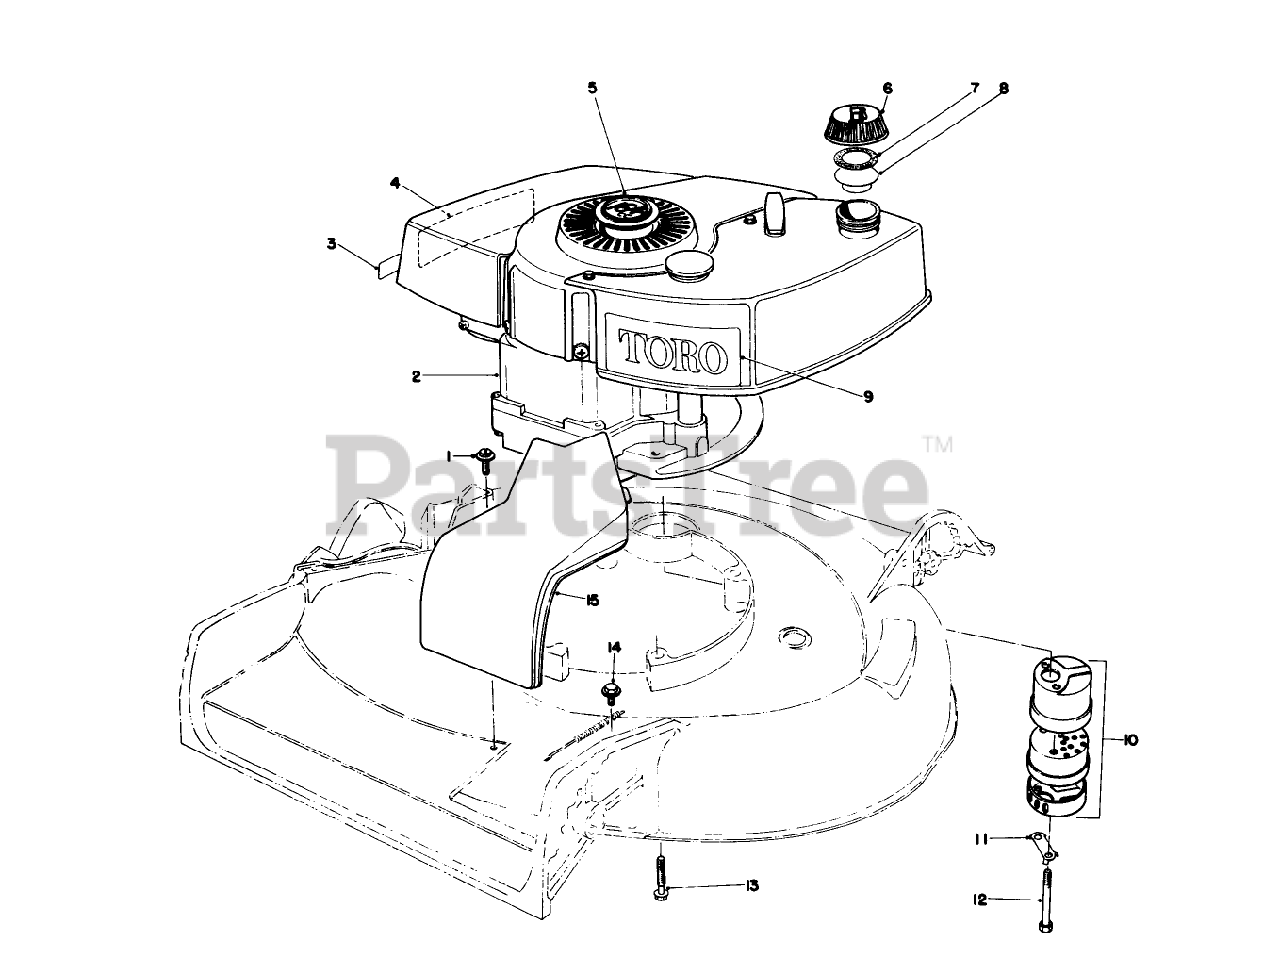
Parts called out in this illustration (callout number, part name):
1	SCREW
2	Engine
7	GASKET
10	Muffler (Incl. Ref. #11 12)
11	CLIP - LOCKING
12	SCREW-HH
13	3/8-16 X 2-3/4 CAPSCR
14	SCREW-THD ROLL, HWH
15	Cover-Belt Drive
